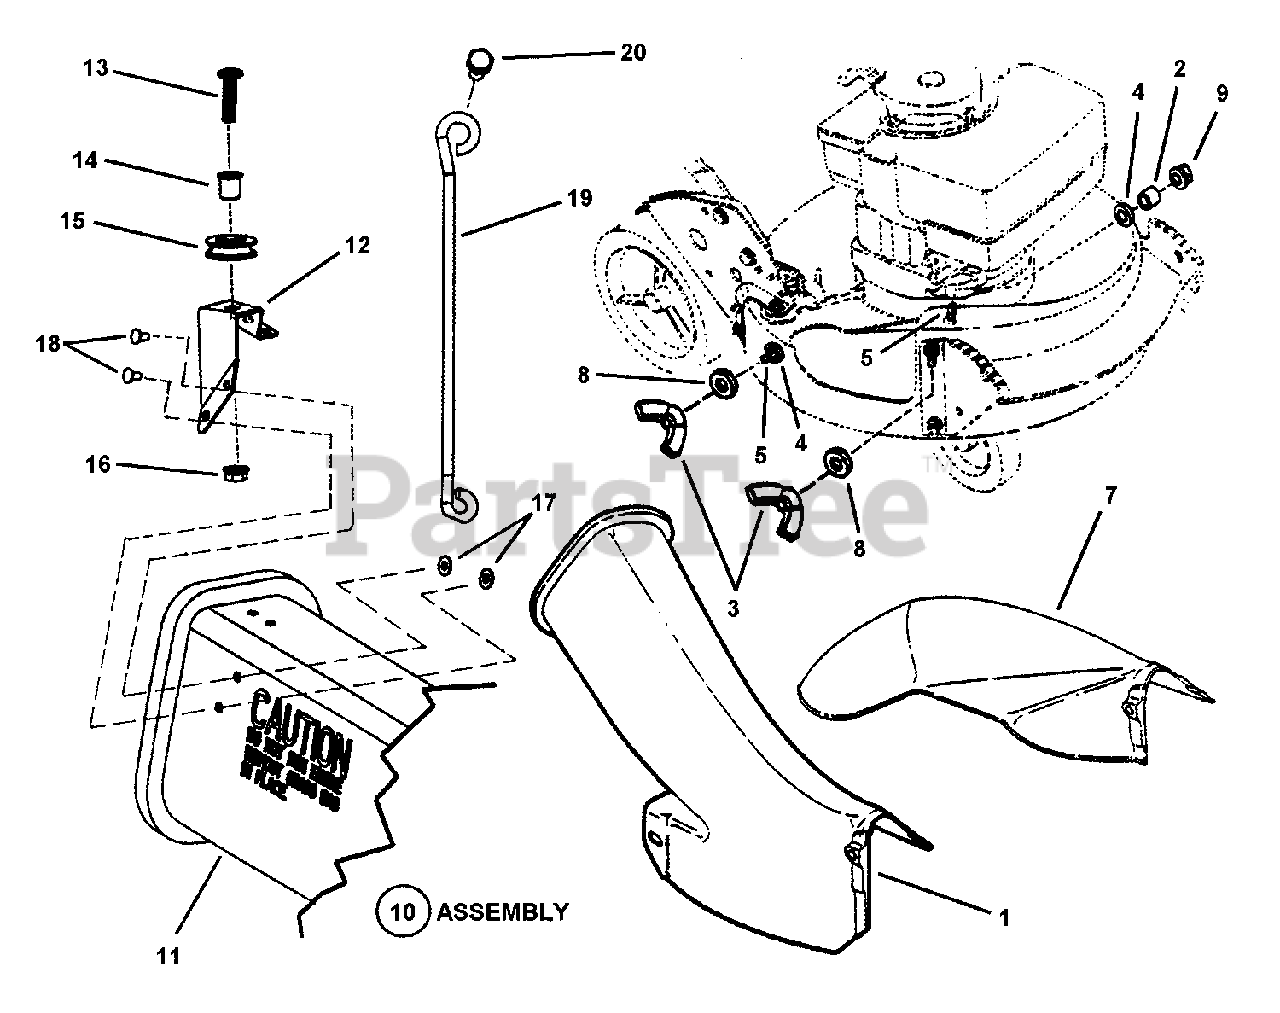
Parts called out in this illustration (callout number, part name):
1	ADAPTER, Grass Bag
2	SPACER, .316 I.D. x .375 O.D. x .310 thick
3	NUT, 5/16-18 Wing (Nylon Patch)
4	RETAINER, 5/16" Bolt
5	BOLT, 5/16-18 x 3/4" Short Neck Carriage GR5
6	KIT, Side Chute (Incl. a quantity of 10 of item 16)
7	CHUTE, Side
8	WASHER, 5/16" Flat
9	NUT, 5/16-18 Hex Large Flange Center Lock
10	ASSEMBLY, Grass Bag Adapter (Incl. items 11 thru 18)
11	ADAPTER, Grass Bag
12	BRACKET, Rope Pulley
13	SCREW, 5/16-18 x 1-1/4" Pan Head Machine
14	BUSHING, Flange
15	PULLEY, Plastic
16	NUT, 5/16-18 Hex Flange Lock GR5
17	WASHER, 15/32" Flat
18	RIVET, 3/16 x .344
19	BRACE, Bag Adapter
20	SCREW, M6 1.0X12MM, Hex Head, CZ
